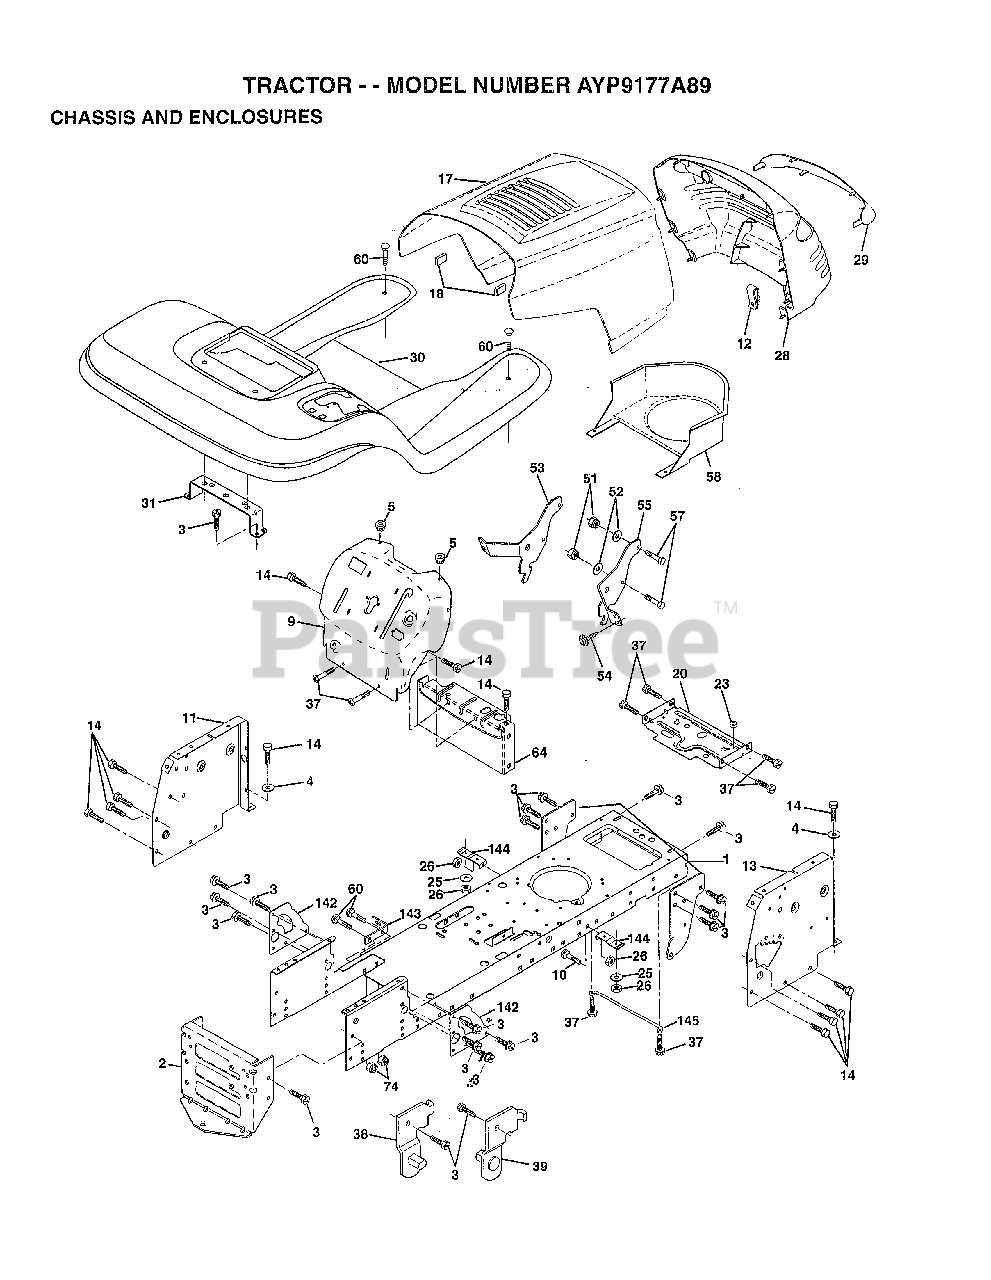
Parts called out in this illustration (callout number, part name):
1	CHASSIS
3	SCREW
4	WASHER
5	BUMPER-HOOD/DASH
11	"PANEL-DASH,LH"
12	CLIP.TINNERMAN
13	"PANEL-DASH,RH"
14	SCREW LT
17	HOOD.STEEL.ASSY
20	"PLATE-MTG,BATT/FU"
25	WASHER
26	NUT
28	GRILL
29	LENS.EURO.W/DECAL
30	FEND/FTREST PNT
31	BRACKET SUPT FEND
37	SCREW LT
38	BRACKET ASM LH
39	BRACKET ASM RH
51	NUT
52	WASHER
53	BRACKET.GRILLE.LH
54	SCREW.HEX.WS.HD
55	BRACKET.GRILLE.RH
58	AIR DUCT
60	BOLT
64	DASH-LOWER
140	BRKT SUSPENSION
142	PLATE.REINFORCEMT
143	"BRKT-S'BAR,CHASSI"
144	BRKT-FOOTREST
145	"ROD POVOT,CHASSIS"
